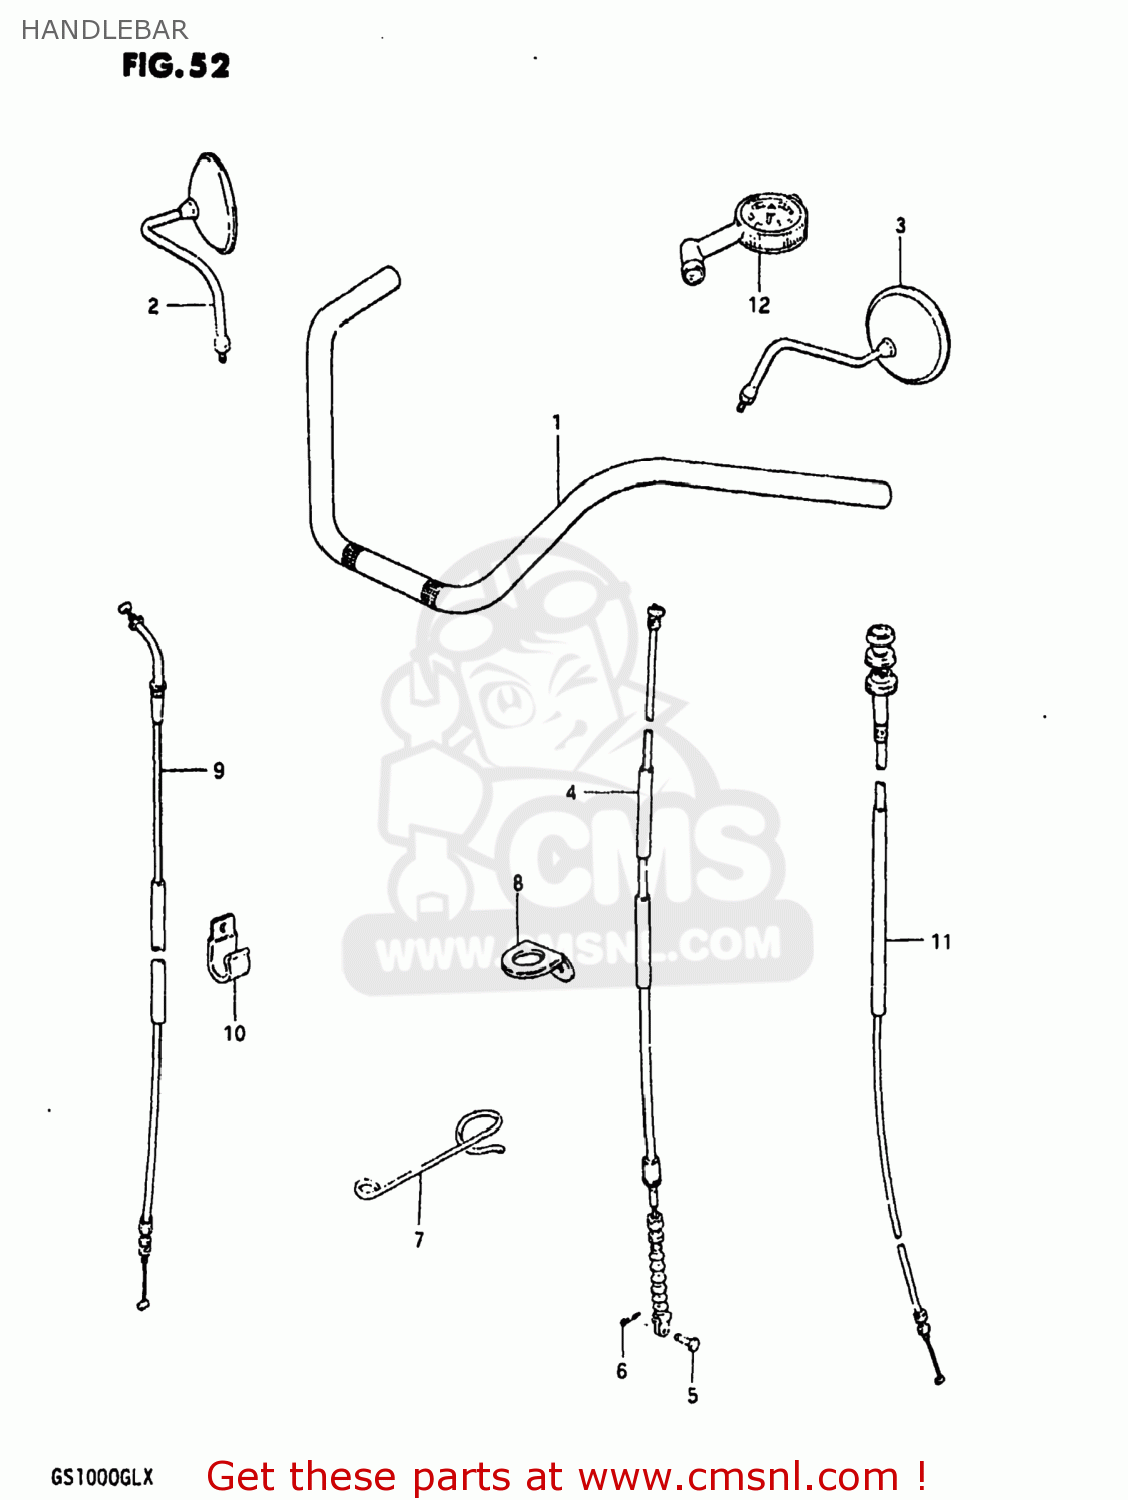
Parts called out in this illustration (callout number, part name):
1	HANDLEBAR
2	MIRROR ASSEMBLY,RIGHT
3	MIRROR ASSEMBLY,LEFT
4	CABLE ASSY,CLUTCH
5	PIN(L:15)
6	PIN
7	GUIDE,CLUTCH CABLE
8	GUIDE,BRAKE HOSE
9	CABLE ASSEMBLY,THROTTLE
10	CLAMP
11	CABLE ASSEMBLY,STARTER
12	GAUGE ASSY,AIR PRESSURE
